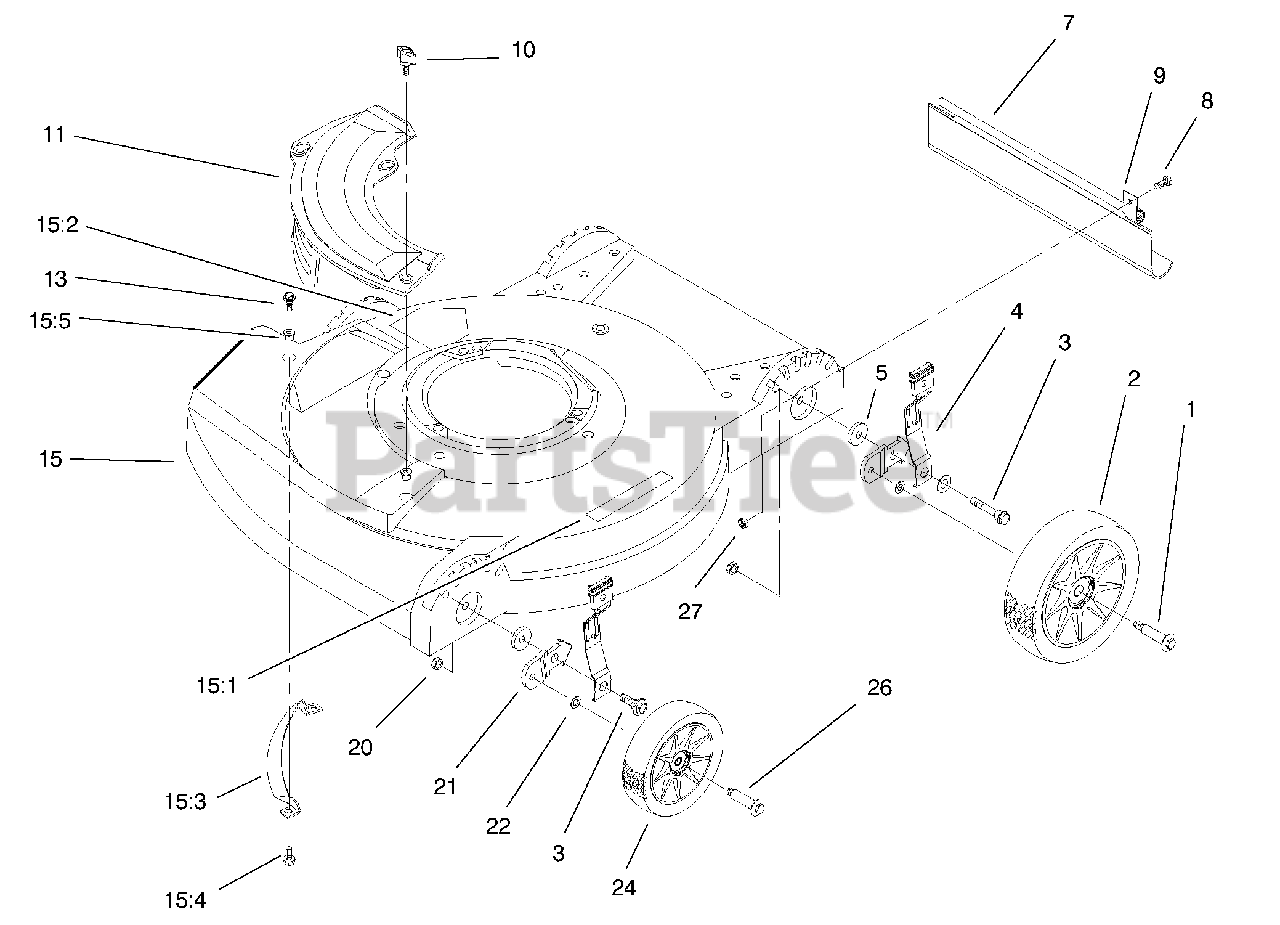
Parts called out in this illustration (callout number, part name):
1	BOLT-SHOULDER
2	8" WHEEL & TIRE ASM
4	SPRING ARM ASM
7	SHIELD - TRAILING
8	Screw
9	CLAMP - SHIELD
11	PLATE-MULCH
13	SCREW-SEMS
15	HOUSING-ASSY-10425 (SERVICES)
15:1	DECAL-WARNING
15:2	DECAL-DANGER
15:3	BAR-TOE
15:4	SCREW-HWH
15:5	GROMMET - PLASTIC
20	NUT-LOCK, NI
21	BRACKET-WHEEL HEIGHT
24	WHEEL & TIRE ASM
26	BOLT-SHOULDER
27	NUT-LOCK NI
